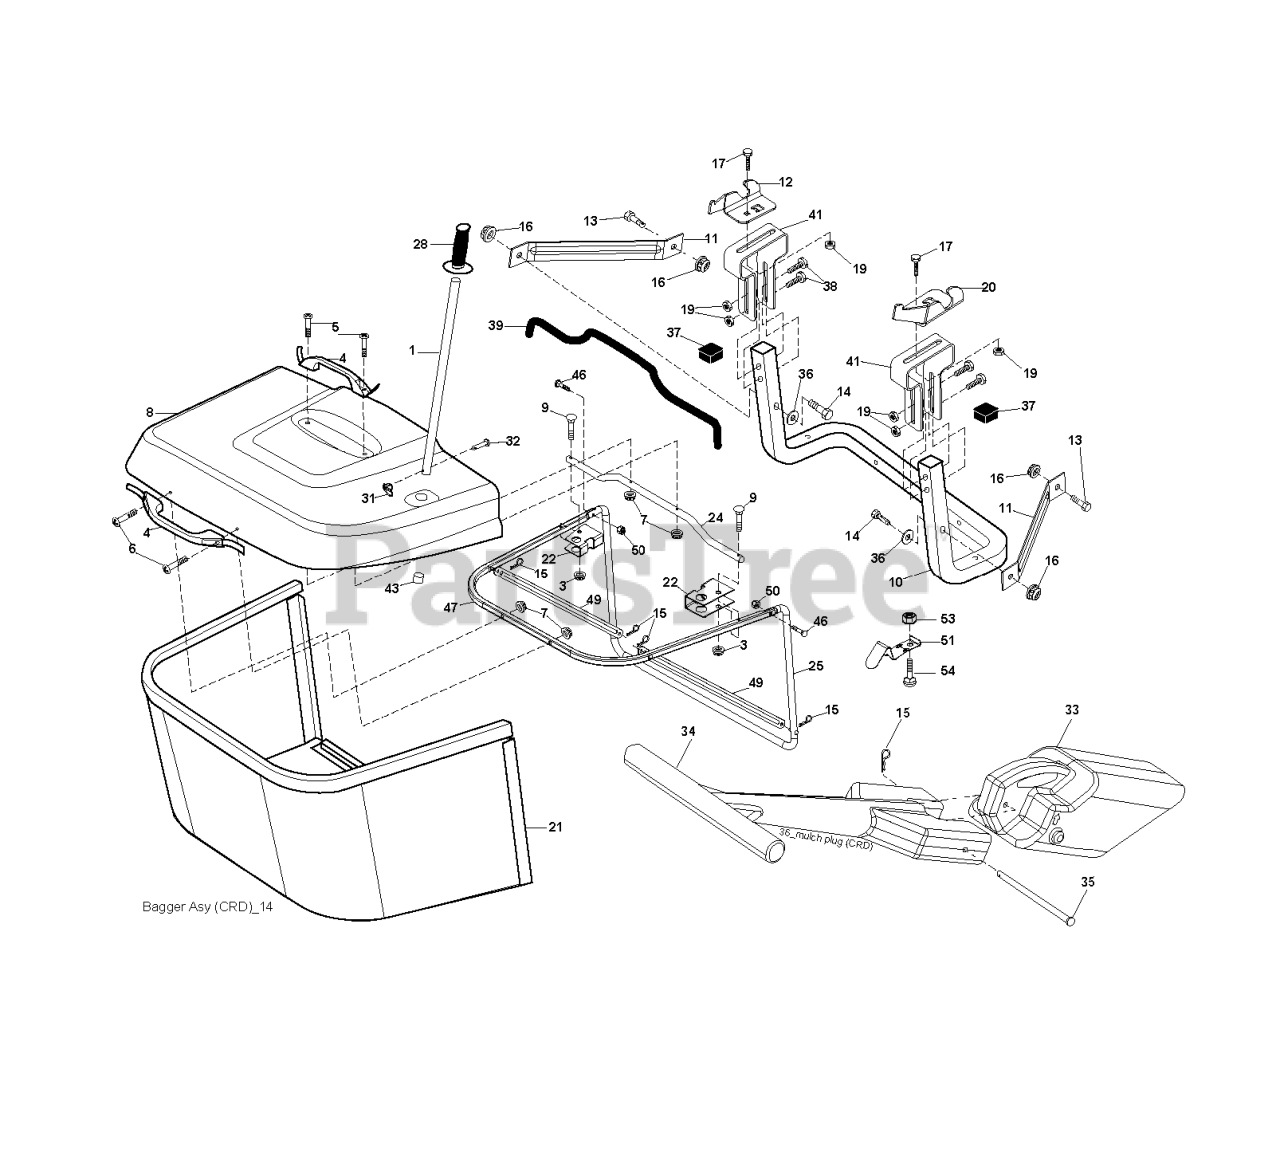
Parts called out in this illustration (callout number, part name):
1	TUBE HANDLE
3	NUT T
4	HANDLE.BAGGER.W/LVRS.BLK.CRD
5	SCREW.PAN.HEAD
6	REPL BY 532 75 00-29
8	COVER.PNT.BGR.CRD.WSLOTS.MS668
9	Bolt Carriage 1/4-20 x 2.25d x Gr.5
10	TUBE
11	BRACKET.SUPPORT.UPPER.BAG.CRD
12	BRKT PIVOT
14	BOLT-HEX EAK
15	RETAINER-SPRNG RB
16	NUT LOCK FLG 3/8-16 UNC
17	RP BOLT 5/16-18 X3/4 ZN/YEL GR
19	NUT LOCK HEX FLANGE 5/16-18
20	BRKT.PIVOT.RH.CRD
21	BAGGER.ASM.CRD.2007
22	BRKT.SIDE.BAG.CRD
24	TUBE.PIVOT.BAG.CRD.BLACK
25	PIPE
28	GRIP.HANDLE.BLACK
31	RETAINER CLIP
32	RIVET,DRILLED
33	MULCH PLUG, CTH150
34	HANDLE.MULCHER.92.CRD (2 2)
36	WASHER
37	Plug Support Bagger CRD
38	BOLT.5/16-18X2.5
39	SEAL.BAGGER.CRD
41	BRKT.VERT.ADJ.BAGGER.CRD
43	PLUG, TUBING END
46	BOLT.CARRIAGE.5/16-18
47	PIPE
49	ROD
50	NUT.71038.31-18.HEX.NYLOCK
51	LATCH
53	NUT
54	BOLT
